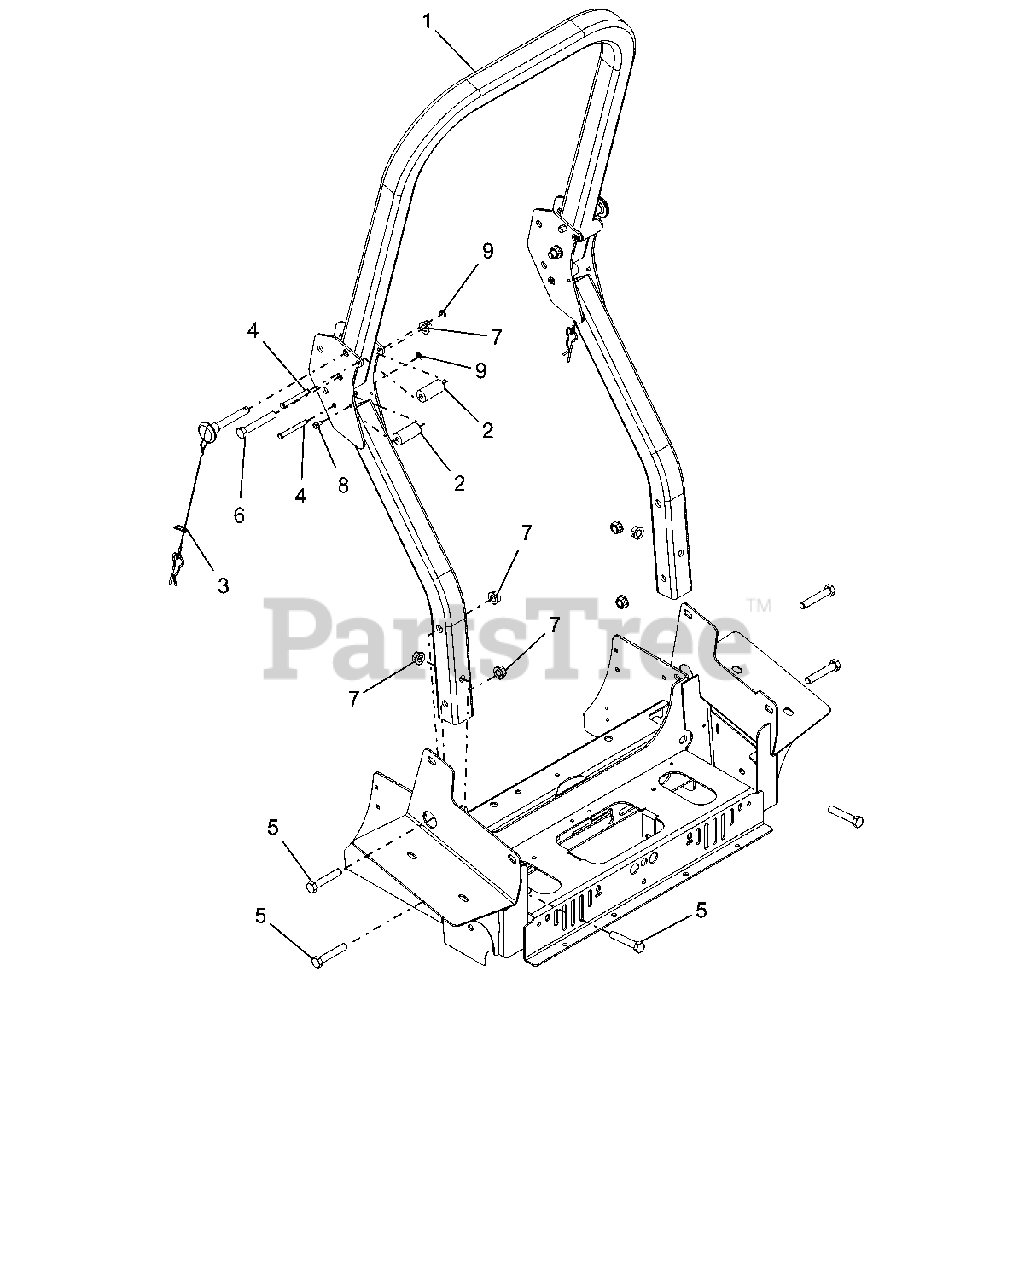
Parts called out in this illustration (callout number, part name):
1	ROPS, PT200/400 REPLACEMENT
2	BUMPER, ROPS ANTI-VIBRATION
3	PIN, ROPS W/LANYARD
4	PIN, 5/16 X 2-9/16 WITH GROOVE
5	BLT-HEX .50-13X2.75 GR5 YWZC
6	BLT-HEX .50-13X3.25 GR5 YWZC
7	NUT-LK-CTR-FLG .50-13 YWZC
8	SCR-TAP .25-20X.50 HWH TR YWZ
9	RING, RETAINING-E .31X.025 - BRIGHT ZINC
